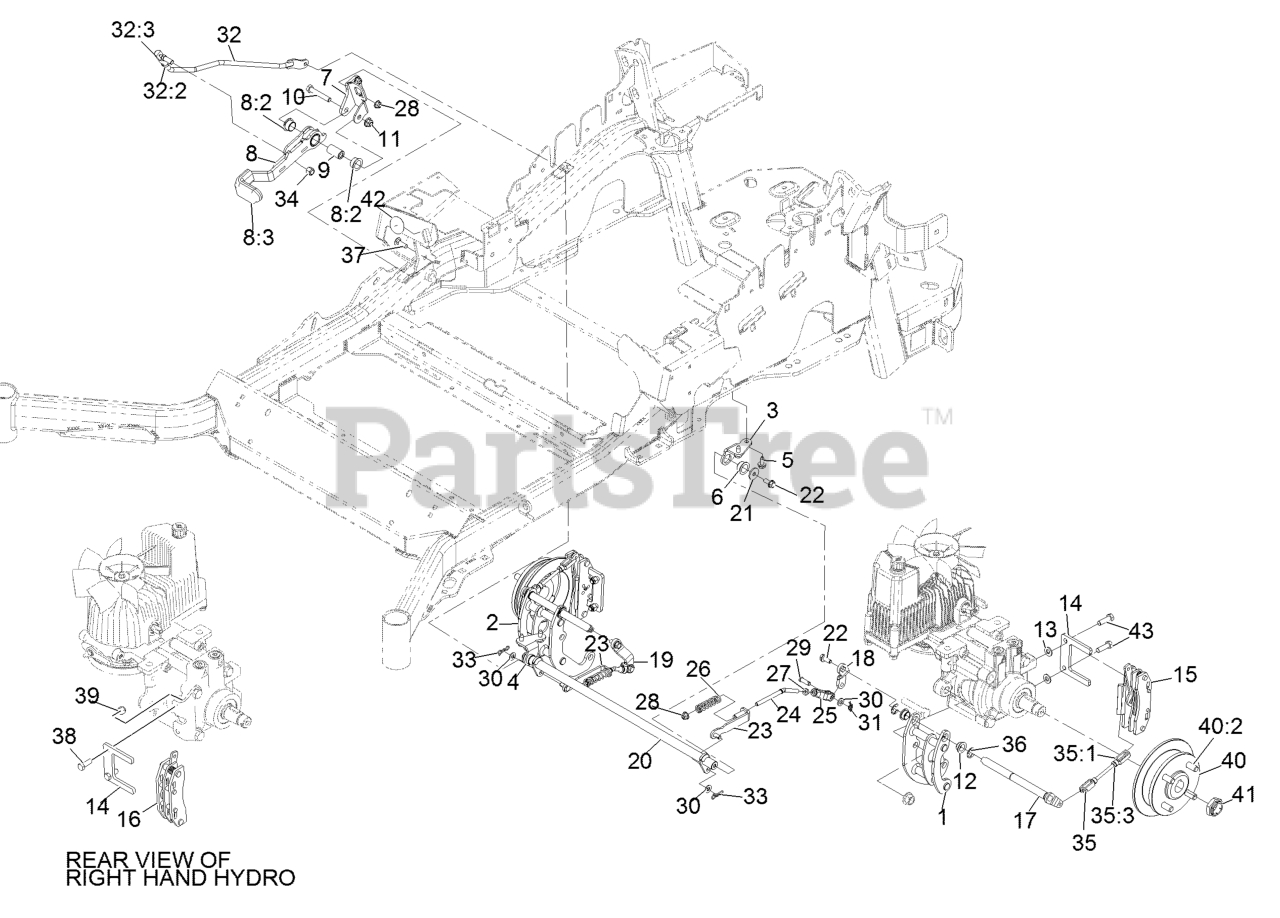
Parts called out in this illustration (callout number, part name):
3	MOUNT-PIVOT, LH
4	MOUNT-PIVOT, RH
5	Screw-HWH 5/16-18 X 3/4 Tf
6	BUSHING-FLANGE
7	BRACKET-MOUNT
8	BRAKE LEVER ASM
8:2	BUSHING-FLANGE
8:3	GRIP-LEVER
9	HANDLE-PIVOT, BRAKE
10	SCREW-HH
11	NUT-HF, NI
12	BUSHING
13	WASHER-FLAT
14	PLATE-MOUNT, BRAKE
15	CALIPER-BRAKE
16	CALIPER-BRAKE, RH
18	ARM-INNER, LH
19	ARM-INNER, RH
20	SHAFT-CROSS
21	WASHER-FLAT
22	SCREW-HHF
23	BRACKET-L
24	LINKAGE-MID
25	YOKE-OFFSET
26	SPRING-COMPRESSION
27	NUT-JAM
28	NUT-HF, NI
29	PIN-CLEVIS
30	WASHER-PLAIN
31	PIN-COTTER, LOCKING
32	FRONT LINKAGE ASM
32:2	END-TIE ROD, RH
32:3	NUT-HJ
33	PIN-COTTER, LOCKING
34	NUT-LOCK
35	REAR LINKAGE ASM
35:3	NUT-JAM
37	BOLT-CARR
38	SCREW-HH
39	NUT-LOCK, NI
40	WHEEL HUB ASM
40:2	STUD-WHEEL
41	LOCKNUT
42	DECAL-COVER
43	SCREW-LOCK, PATCH
